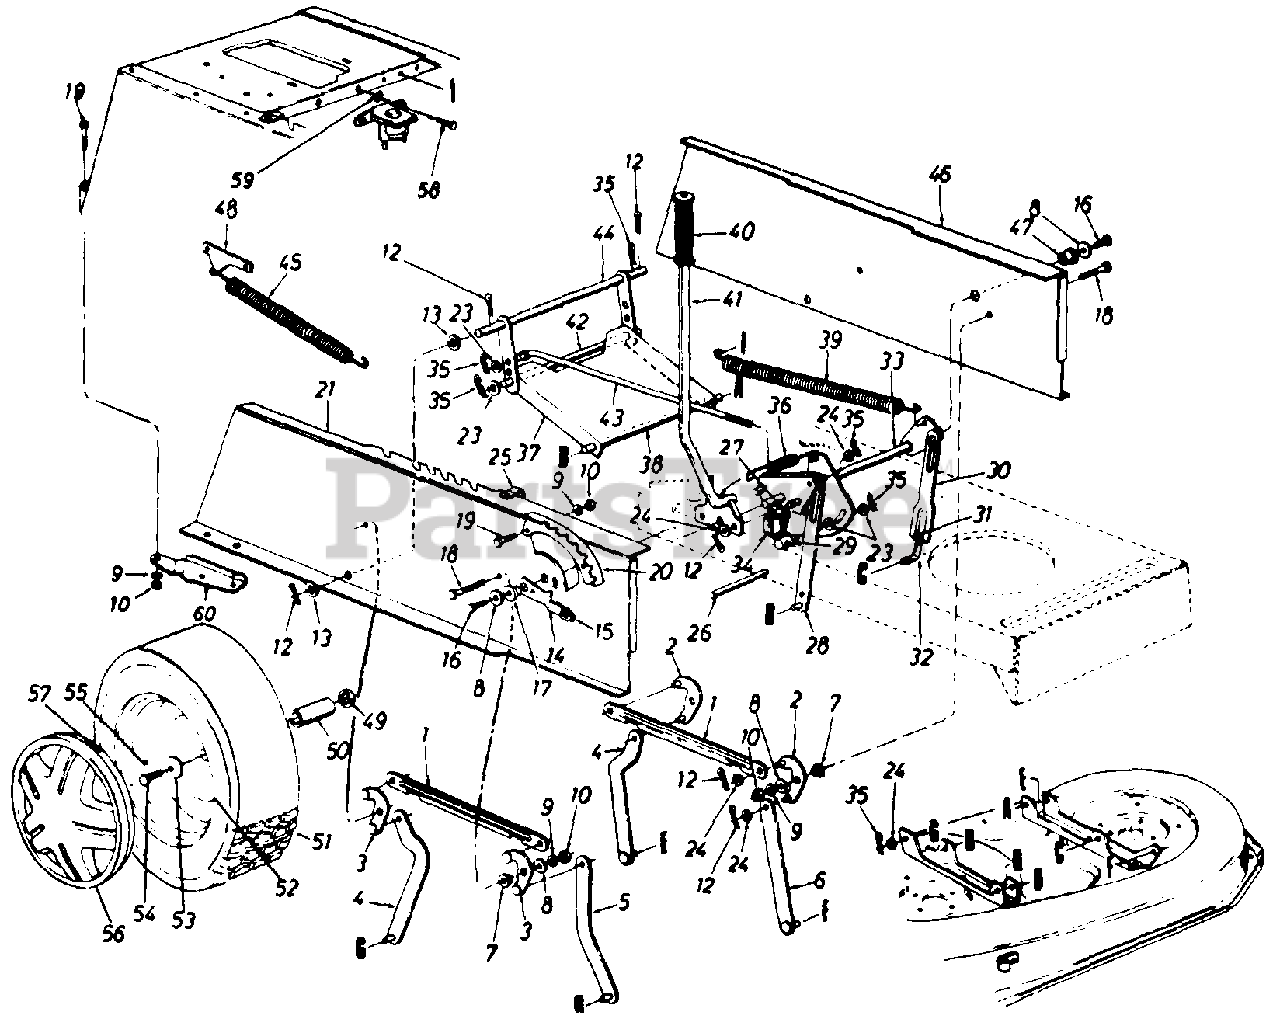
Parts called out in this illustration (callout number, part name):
1	Connecting Rod
2	Pivot Link Ass'y. - L.H.
3	Pivot Link Ass'y. - R.H.
7	Shld. Spacer .318" I.D.
8	Fl-Wash. .344" I.D. x .62" O.D.
9	L-Wash. 5/16" I.D.
10	Hex Nut 5/16-18 Thd.
12	Cotter Pin 1/8" Dia.
13	Fl-Wash. .635" I.D. x 1.0" O.D.
14	Deck Lift Stop
16	Hex TT-Tap Scr. 5/16-18 x .75"
17	Flange Brg. .63" I.D.
18	Hex Wash. Hd. Scr. 5/16-18 x .875"
19	Hex Bolt 5/16-18 x .75" Lg.
20	Index Brkt.
21	Upper Frame - R.H.
23	Fl-Wash. .385" I.D. x .87" O.D.
24	Fl-Wash. .531" I.D. x .93" O.D.
26	Running Board Rod
27	Hex Tap Scr. #12 x .375"
31	Hex Nut 1/2-20 Thd. (Gr. 5)
32	Lift Link Adjuster
35	Inter. Cotter Pin 3/8" Dia.
36	Extension Spring
37	Stabilizer Bracket
38	Shaft 1/2" Dia. x 10.28" Lg.
39	Extension Spring
40	Grip (Lift Handle)
41	Deck Lift Handle Ass'y.
43	Disengagement Rod
44	Stabilizer Shaft Ass'y.
45	Extension Spring
46	Upper Frame - L.H.
47	Flange Brg. .632" I.D.
48	Deck Spring Brkt.
49	Fl-Wash. .76" I.D. x 1.49" O.D.
50	Sleeve .75" I.D. x 1.0" O.D.
52	Wheel Rim Only
53	Bell-Wash. .345" I.D. x .88"
54	Hex L-Bolt 5/16-24 x .75" Lg.
55	Air Valve
57	Spring Clip
58	Hex Wash. Hd. TT-Tap Scr. 1/4-20 Thd.
59	Ext. L-Wash. 1/4" I.D.
